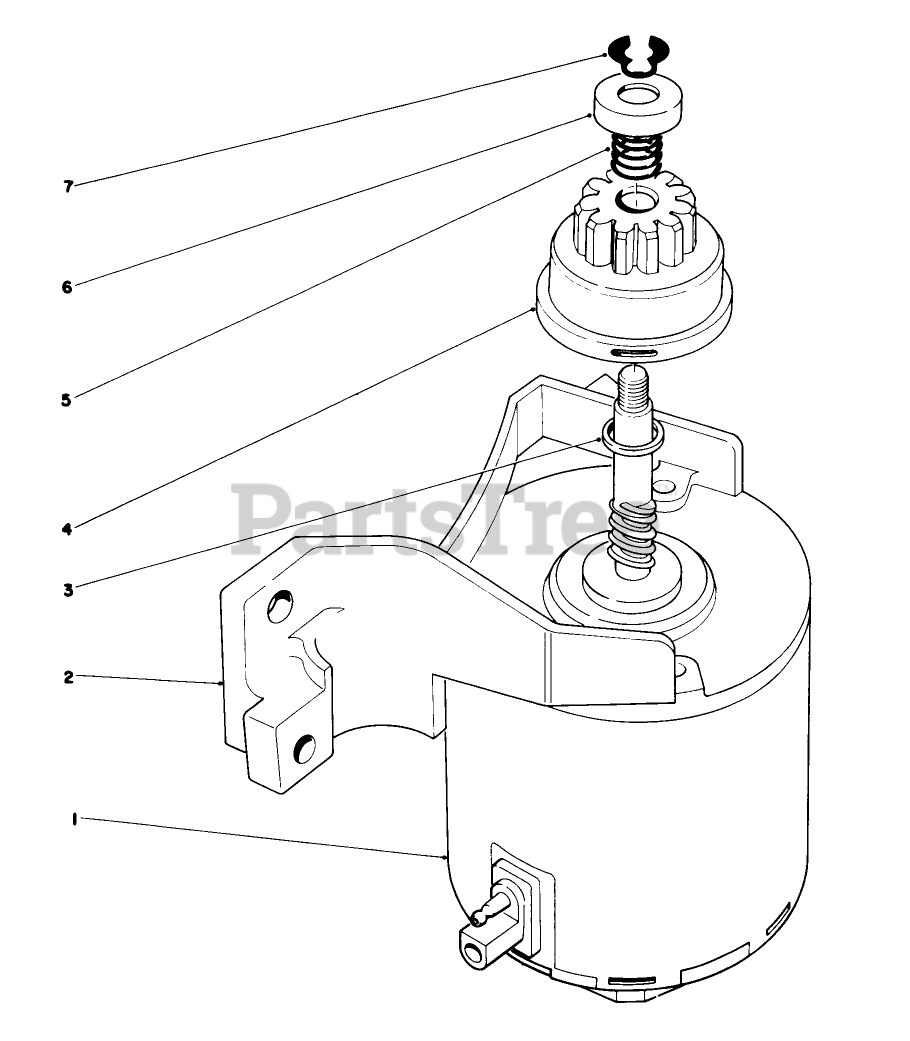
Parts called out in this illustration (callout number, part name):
1	END FRAME W/BRUSH
2	BRKT END FRAME
3	SPACER
4	PINION ASM
5	COMPRESSION SPRING
6	PINION STOP
7	RING-RETAINING
